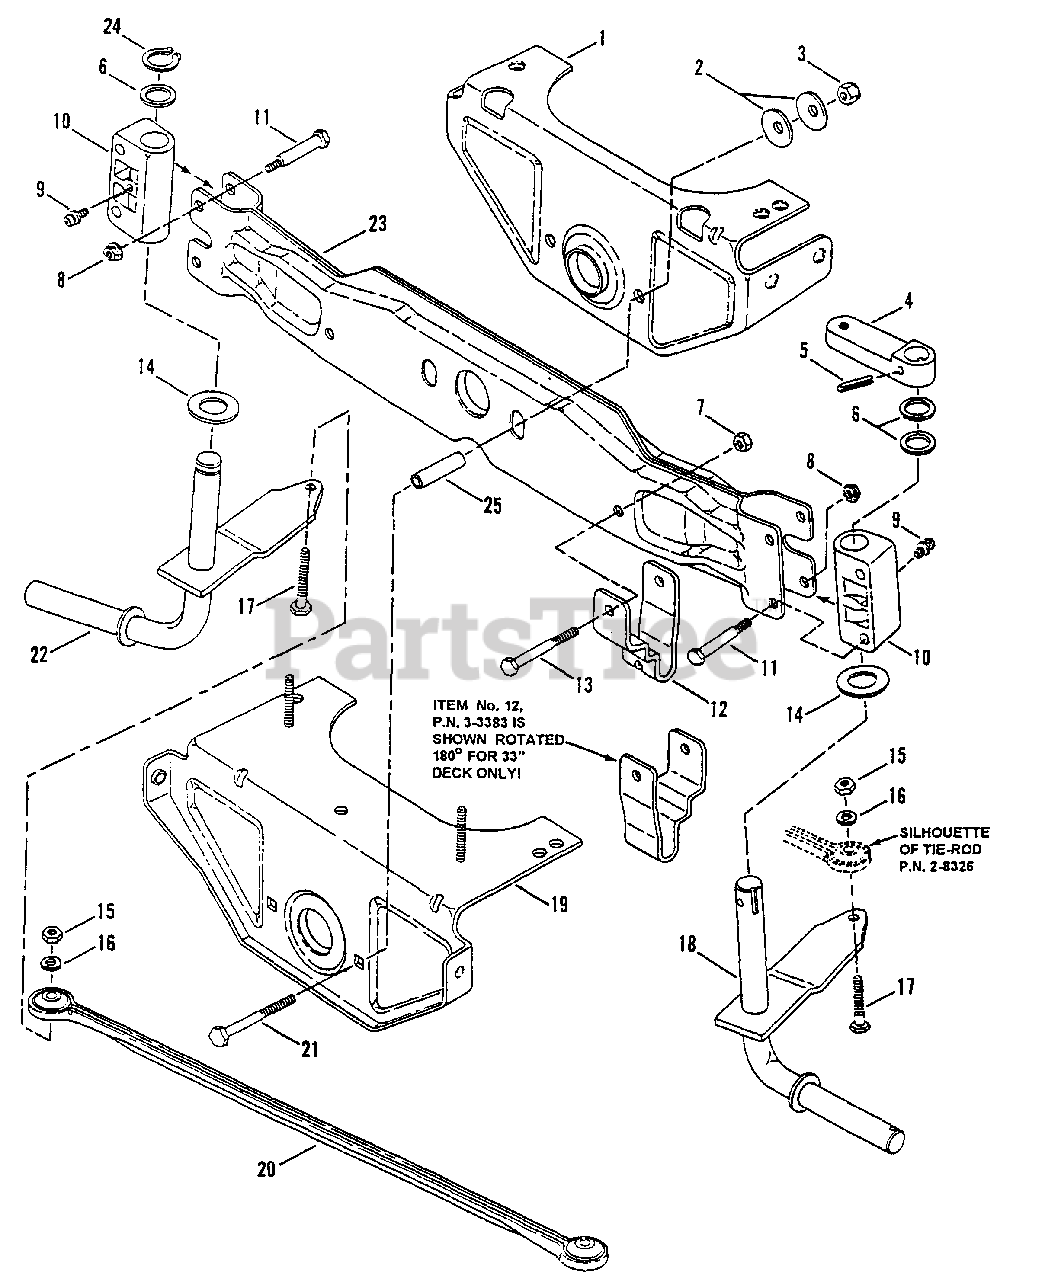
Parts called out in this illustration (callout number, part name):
1	BRACKET, Front Axle (Rear)
2	WASHER, Cone
3	NUT, 3/8-16 Nyloc
4	ARM, Steering
5	ROLL-PIN, 1/4 x 1-1/4
6	WASHER, Shim
7	NUT, 5/16-18 Center Lock
8	NUT, 1/4-20 Hex Flg. Top-Lock Grade A
9	LUBE FITTING, Straight (press-fit for .187 dia. Hole)
10	BEARING, Spindle
11	BOLT, 1/4-20 x 1 41/64 Shldr
12	BRACKET, Deck Hanger
13	SCREW, 5/16-18 x 2 1/2 Hex Head Cap Grade 2
14	WASHER, Thrust
15	NUT, 3/8-16 Hex, Grade 5
16	WASHER, 3/8 Split Lock
17	SCREW, 3/8-16 x 1-1/2 Hex Head Cap, Grade 5
18	SPINDLE ASSY., Left Hand, Short
19	BRACKET ASSEMBLY, Axle (Front)
20	TIE-ROD
21	BOLT, 3/8-16 x 3 Hex Head Grade 5
22	SPINDLE ASSY., Right Hand, Short
23	AXLE, Front
24	RING, Retaining
25	SPACER
